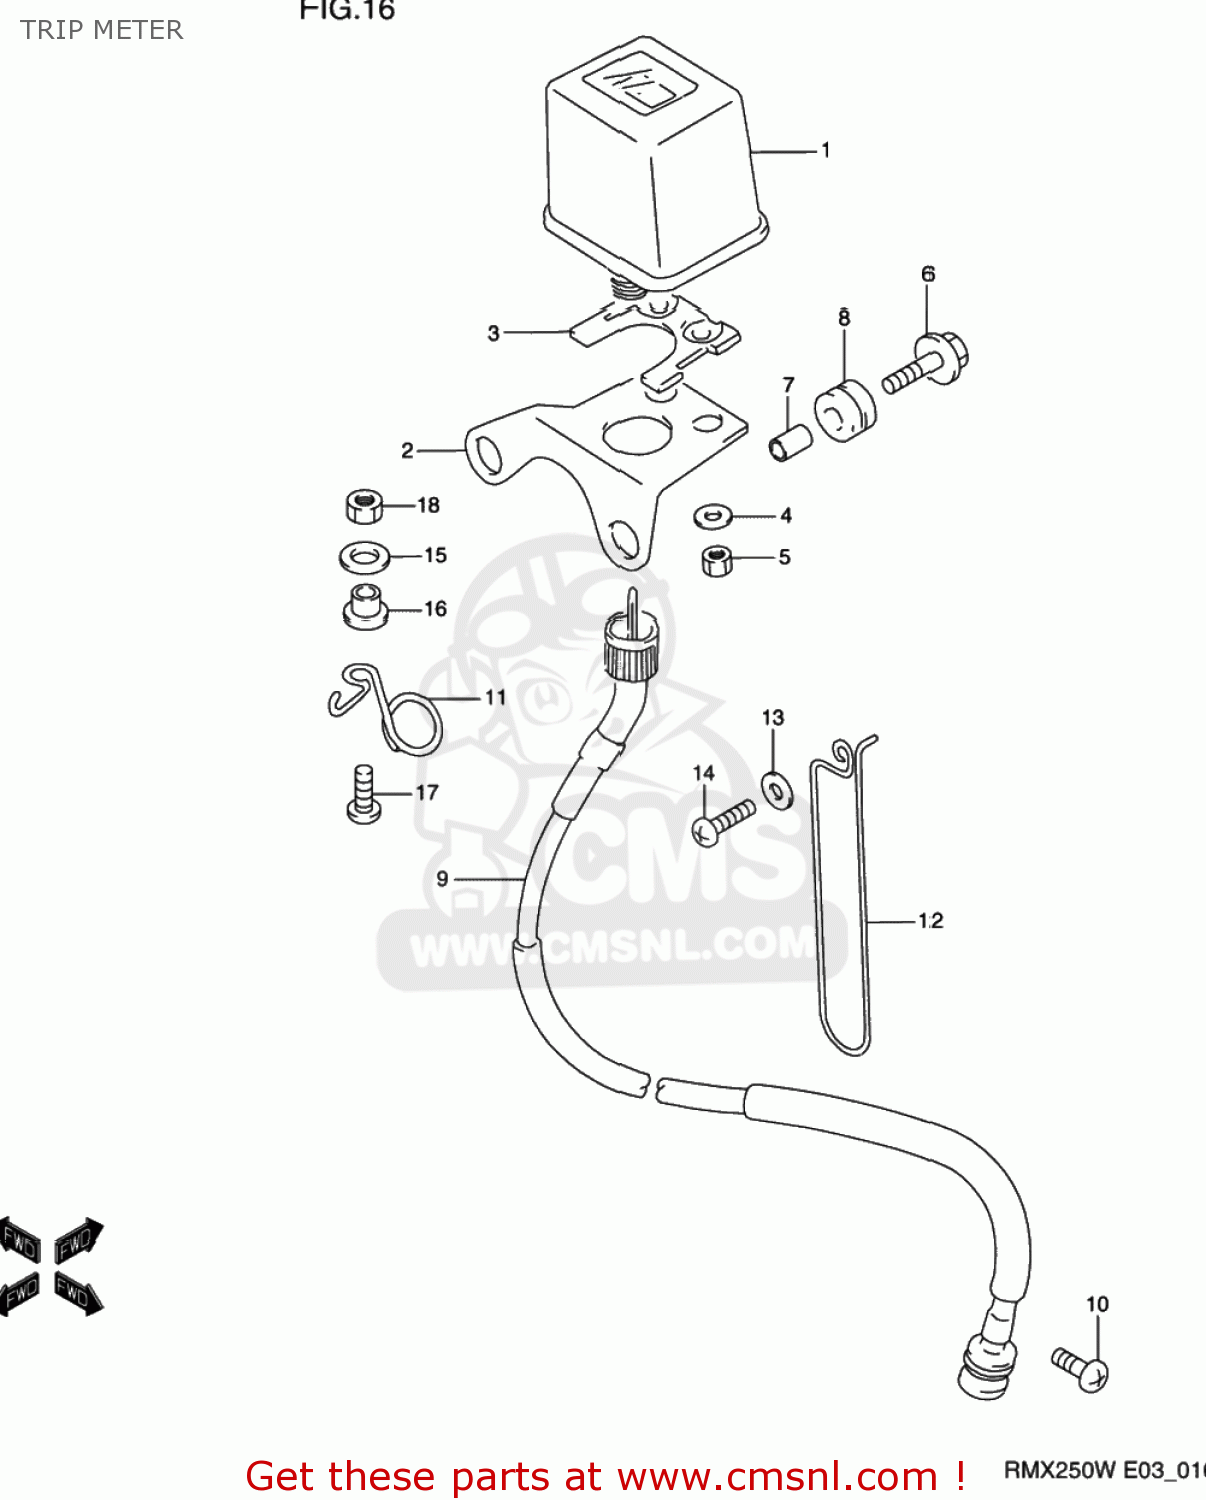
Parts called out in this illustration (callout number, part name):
1	TRIP METER
2	BRACKET
3	CUSHION
4	WASHER (4.3X13X0.80)
5	NUT
6	BOLT(6X25)
7	SPACER(6.1X8X9.5)
8	CUSHION
9	CABLE ASSY,SPEEDOMETER
10	SCREW
11	GUIDE,SPEEDOMETER CABLE
12	GUIDE,METER CABLE NO.2
13	WASHER(6.5X20X1.6)
14	SCREW
15	WASHER(6.5X18X1.6)
16	WASHER
17	SCREW
18	NUT 6MM
